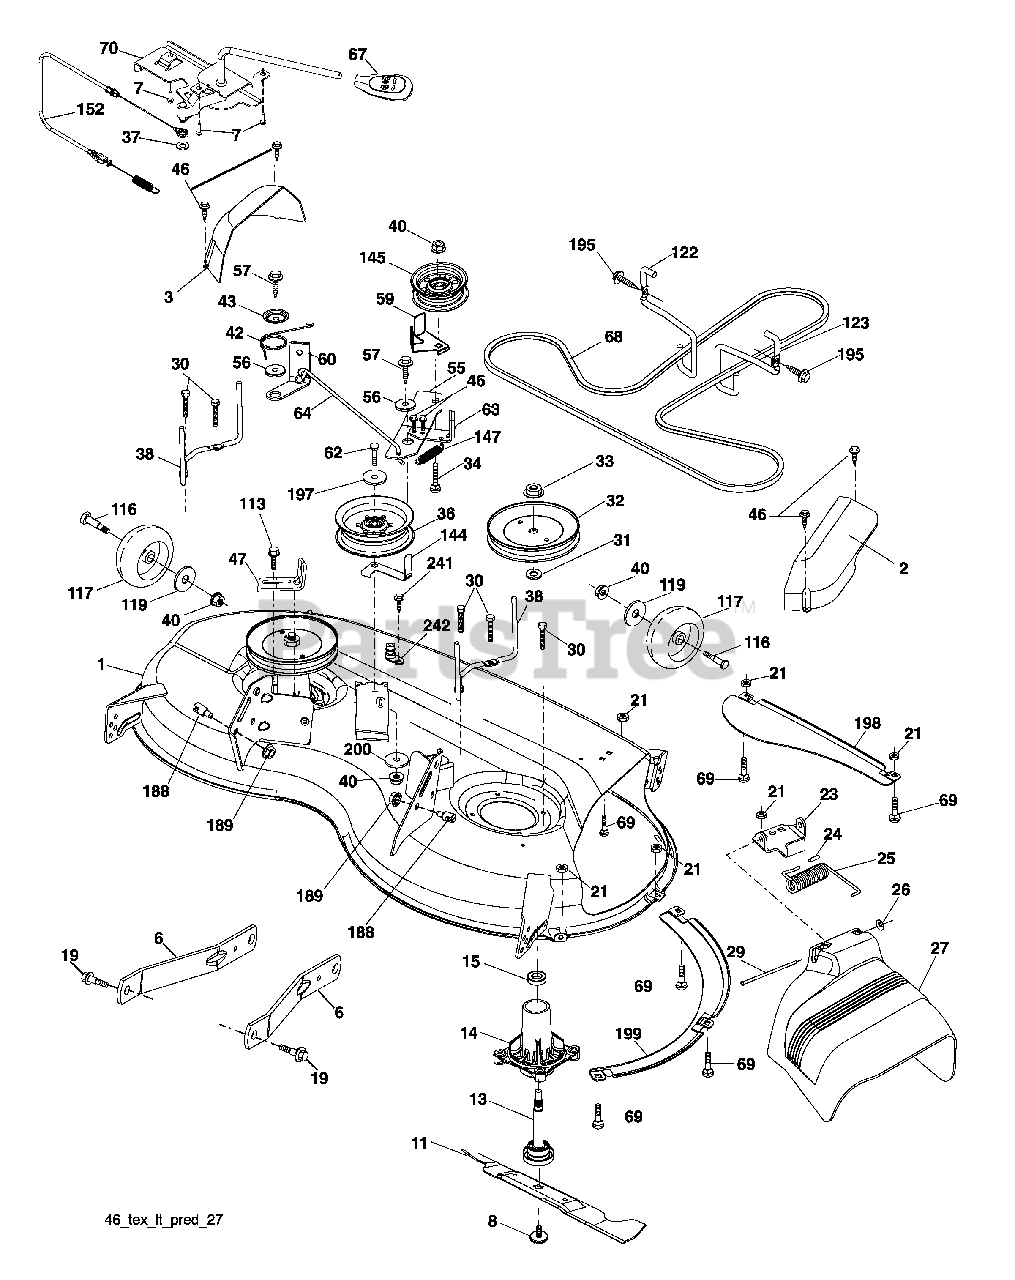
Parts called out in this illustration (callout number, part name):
1	Mower Housing
2	Cover Mandrel RH
3	Cover Mandrel LH
6	Arm Suspension
7	Screw #10 x 0.750
8	Bolt/Washer Asm 7/16-20 unf
11	Blade Mower
13	Shaft Assembly, Mandrel
14	Housing, Mandrel
15	Bearing, Ball, Mandrel
19	Bolt, Shoulder
21	Nut
23	Bracket, Deflector
24	Cap, Sleeve
25	Spring, Torsion, Deflector
27	Shield, Deflector
29	Rod, Hinge
30	Screw Thdrol Rolling Wsh Hd
31	Washer, Spacer
32	Pulley, Mandrel
33	Nut, Toplock, Flanged
34	Bolt Carr Sh. 3/8-16 x 1-1/2 Gr. 5
36	Pulley, Idler, Flat
37	Washer 13/32 x 13/16 x 16 Ga.
38	Keeper Belt LH Mandrel
40	Nut, Lock Flg. 3/8-16 unc
42	Spring Trosion Brake
43	Spring Torsion Retainer
47	Bracket Clutch Cable
55	Arm, Idler
56	Spacer, Retainer
57	Screw Hexwsh Thd 3/8-16 x 1
59	Guard, Tuv Idler (94)
60	Arm Brake Mower LH
62	Bolt 3/8-16 unc x 2-1/4 Gr. 5
63	Arm Brake Mower
64	Linkage Brake
67	Handle, Clutch Cable
68	V-Belt
69	Bolt
70	Clutch Asm. Cable
113	Screw 5/16-18
116	Bolt, Shoulder
117	Wheel, Gauge
119	Washer 13/32 x 1-1/4 x 12 Ga.
122	Keeper Belt Eng. LH
123	Keeper Belt Eng. RH
144	Keeper Belt
145	Pulley Idler
147	Spring Return
152	Cable Clutch Manual w/Spr.
188	Stud Fastener
189	Nut Lock Hex Flange
195	Screw 3/8-16 x 3/4
197	Washer 13/32 x 13/16 x 12 Ga.
198	Baffle Center Front
199	Baffle Front RH
200	Washer 13/32 x 1 x 1/2 11 Ga.
242	Washout Port
